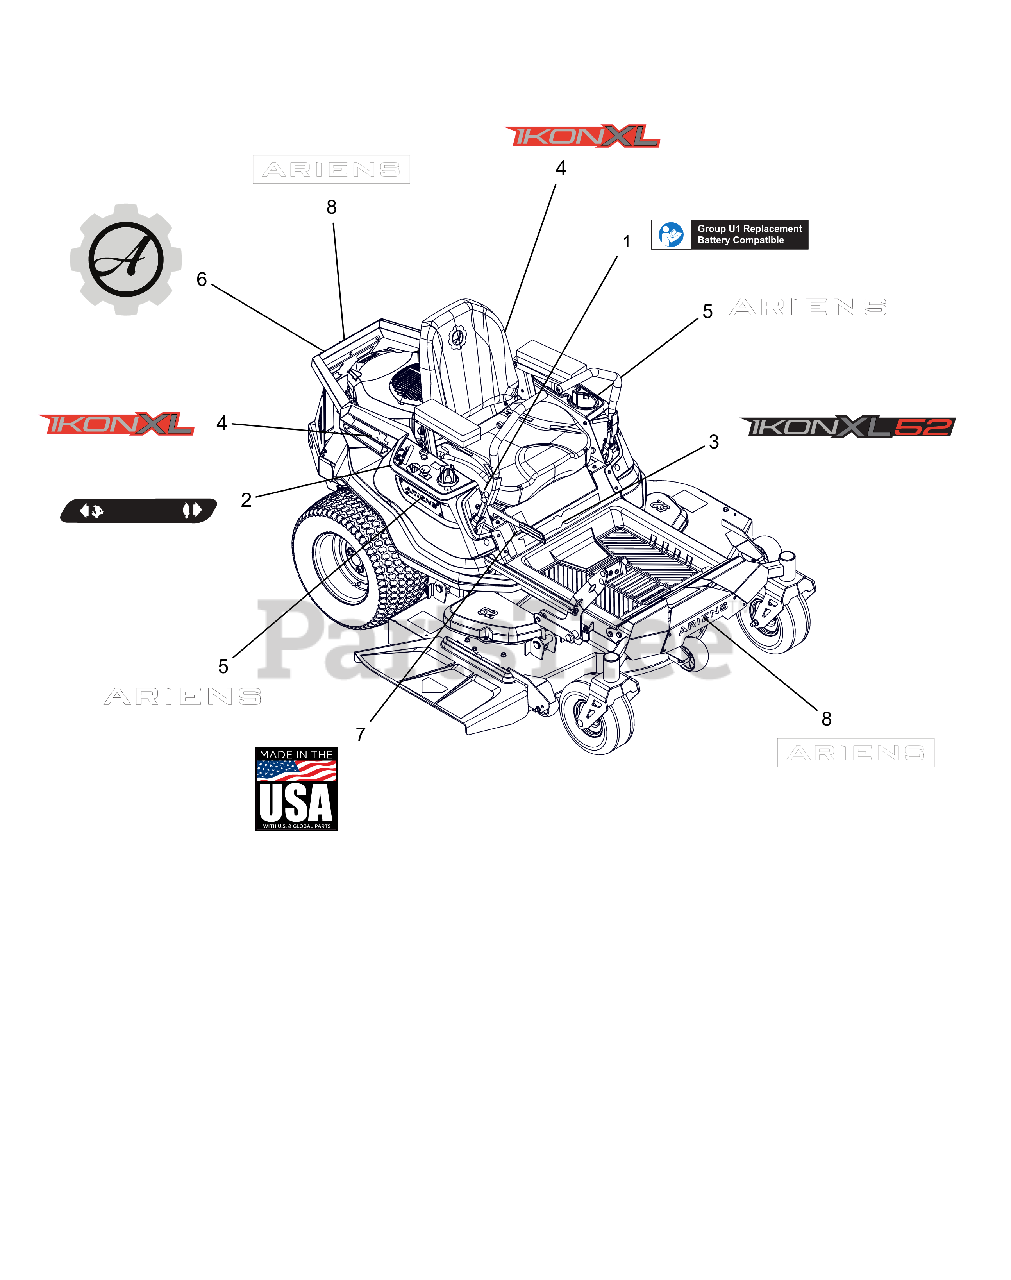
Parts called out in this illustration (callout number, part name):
1	DECAL, U1 BATTERY REPLACEMENT
2	DECAL, DASH DECAL
3	DECAL, IKON-XL 52"
4	DECAL, IKON-XL
5	DECAL, ARIENS (6.50")
6	DECAL, ARIENS-GEAR BADGE
7	DECAL, MADE IN USA
8	DECAL - ARIENS 9.625"
